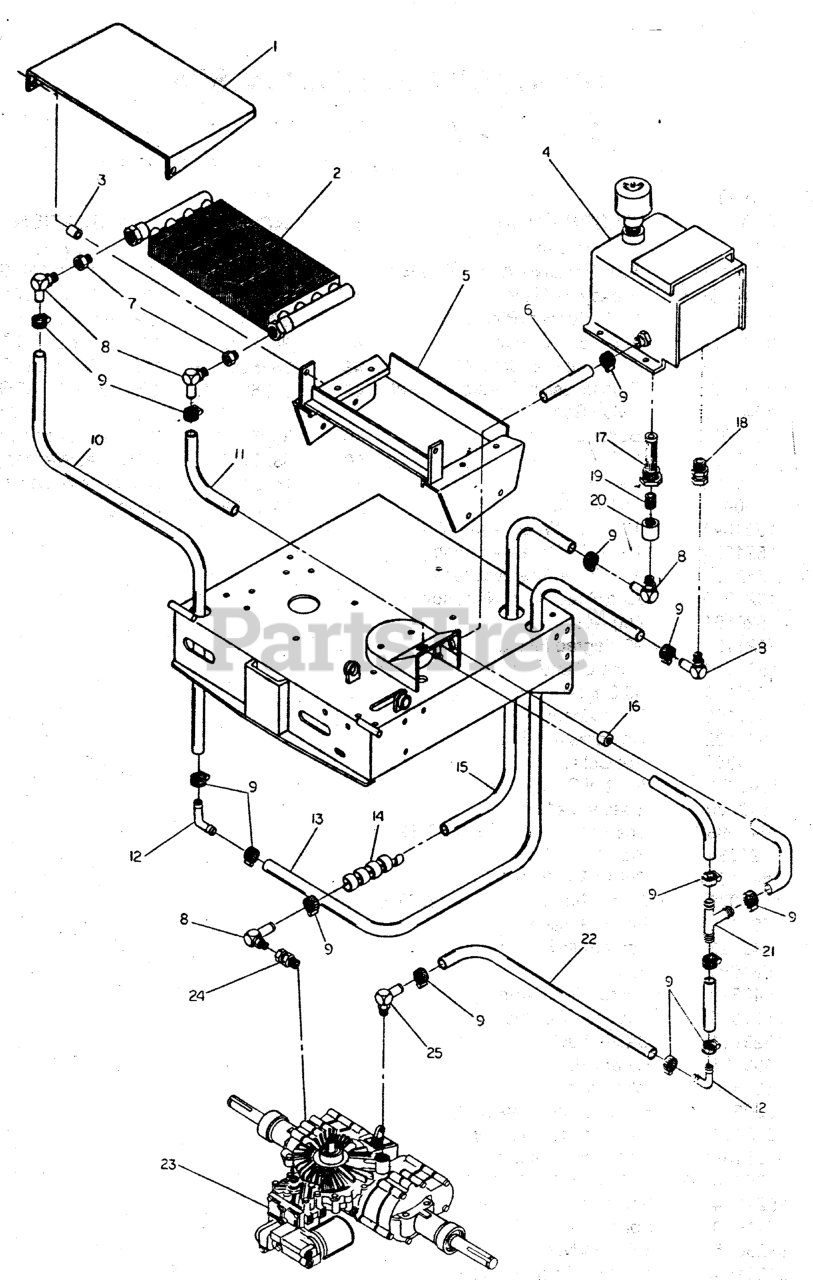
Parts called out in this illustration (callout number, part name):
1	OIL COOLER HOOD
2	OIL COOLER
3	SPACER, .27 x .75 x .69
4	Hydro Tank
5	Oil Cooler Shroud
6	Hose, 7-1/2"
7	Bushing
8	FITTING, 90 Degrees 1/2" NPT
9	CLAMP, #10 Hose
10	Hose, 19"
11	Hose, 16-1/2"
12	90 Degree Fitting
13	Hose, 36"
14	Plastic Hose Coil
15	Inlet Hose
16	Orifice
17	STRAINER
18	FITTING, Straight Swivel
19	NIPPLE, 1/2" NPT Close
20	COUPLER, 1/2" NPT
21	Tee Fitting
22	Hose, 6"
23	850 Transaxle
24	INSERT, Bearing Shoulder
25	FITTING, 90 Degrees 7/8" O-Ring
